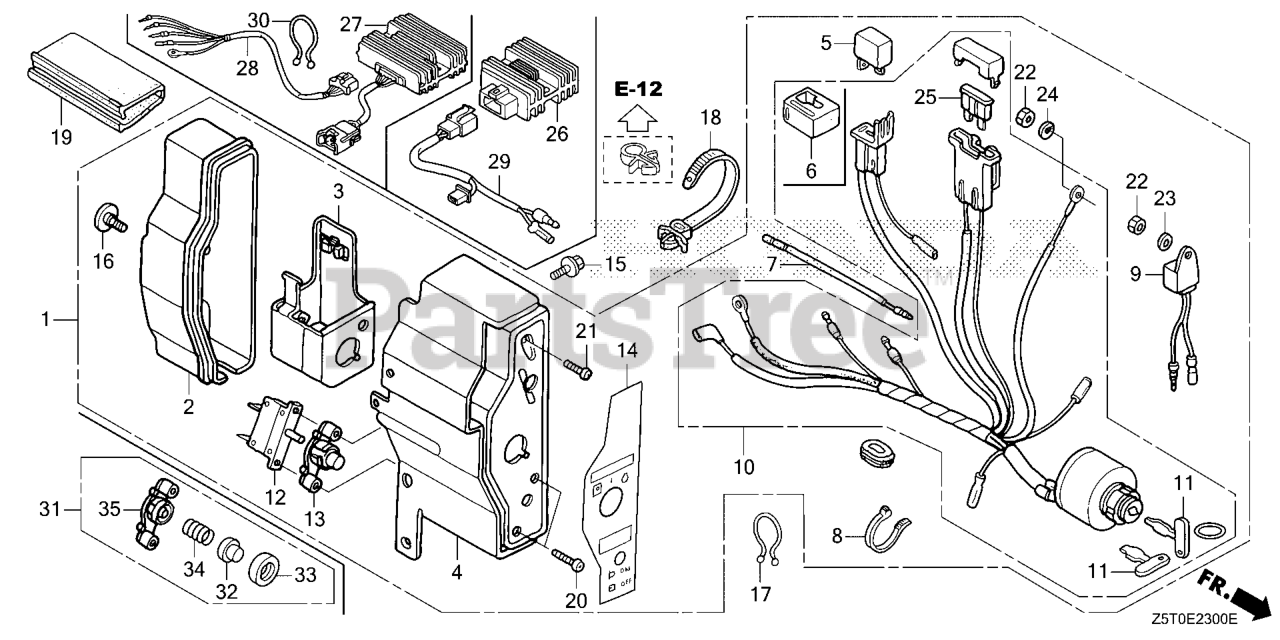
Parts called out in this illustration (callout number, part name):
1	BOX ASSY., CONTROL (18A) *R280* (POWER RED)
2	CASE, CONTROL
3	BRACKET, CASE MOUNTING
4	PANEL, CONTROL *R280* (POWER RED)
8	BAND
10	SWITCH ASSY., COMBINATION (18A)
11	KEY
14	MARK, CONTROL BOX (EXP)
15	BOLT, FLANGE (6X12) (CT200)
16	SCREW, SPECIAL (6X12)
17	CLIP, PURSE LOCK
18	STRAP, CABLE (118MM) *NH1L* (Honda Code 1170653). (BLACK)
19	TUBE, FASTENER (30)
21	SCREW, PAN (4X12)
22	NUT, HEX. (4MM)
24	WASHER, SPRING (4MM)
25	FUSE, BLADE (25A)
27	RECTIFIER ASSY., REGULATOR (20A)
28	SUB-WIRE HARNESS ASSY.
30	CLIP, PURSE LOCK
